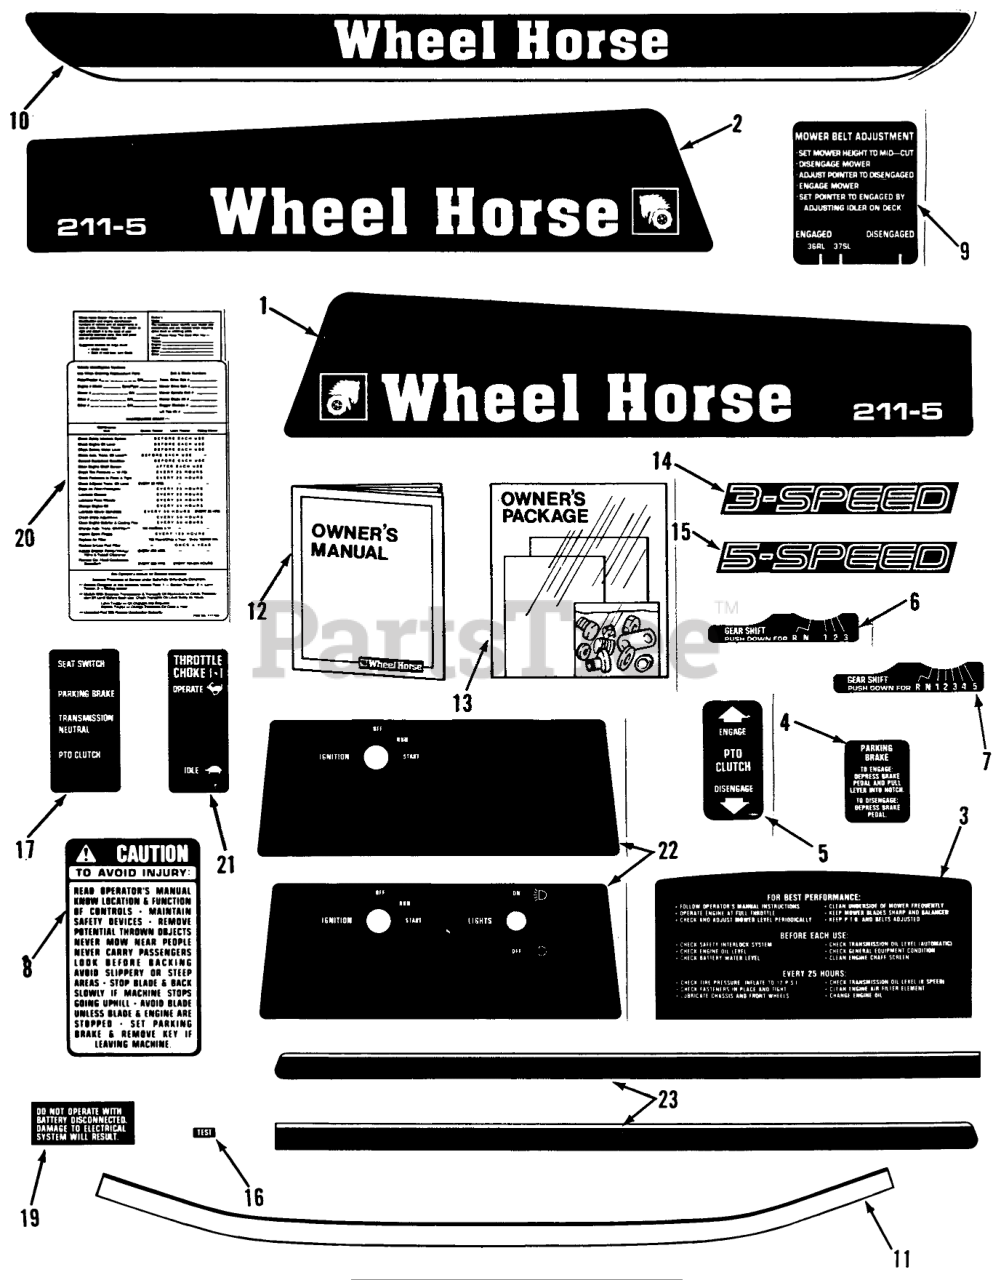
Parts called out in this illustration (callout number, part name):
1	DECAL HOOD RH
1	Decal-Hood RH 211-5 Only
2	DECAL HOOD LH
2	Decal-Hood LH 211-5 Only
3	DECAL REAR HOOD
4	DECAL PARKING BRAKE
5	DECAL PTO CLUTCH
6	Decal-Shift 3-Speed
7	Decal-Shift 5-Speed
8	DECAL CAUTION
9	Decal-Belt Gage
10	Decal-Rear Fender
11	DECAL FRONT HOOD
12	Owner-s Manual-Tractor
13	Screw
13	Washer-Sealing
14	DECAL 3SPD
15	DECAL 5SPD
16	Decal-Test 211-5 Only
17	Decal-Indicator Lights 211-5 Only
19	DECAL ELECT SYSTEM
20	Decal-Maintenance
21	DECAL-THROTTLE
22	Decal-Back Plate 211-3 Only
23	DECAL HOOD STRIPE RH
